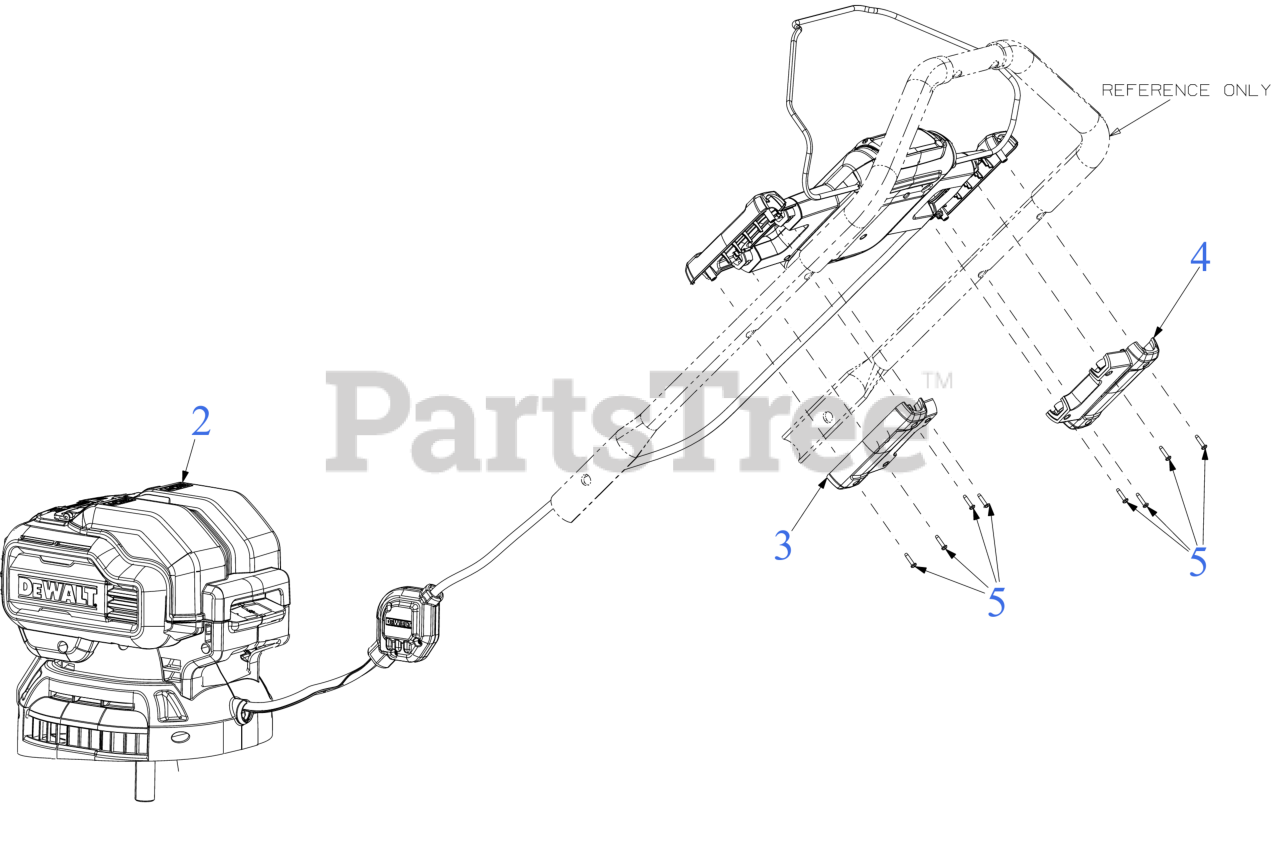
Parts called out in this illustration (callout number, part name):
3	HANDLE PANEL COVER (REAR) (LH) (YELLOW)
4	HANDLE PANEL COVER (REAR) (RH) (YELLOW)
5	SCREW-TAP PLASTIC #6-19 x 0.63
